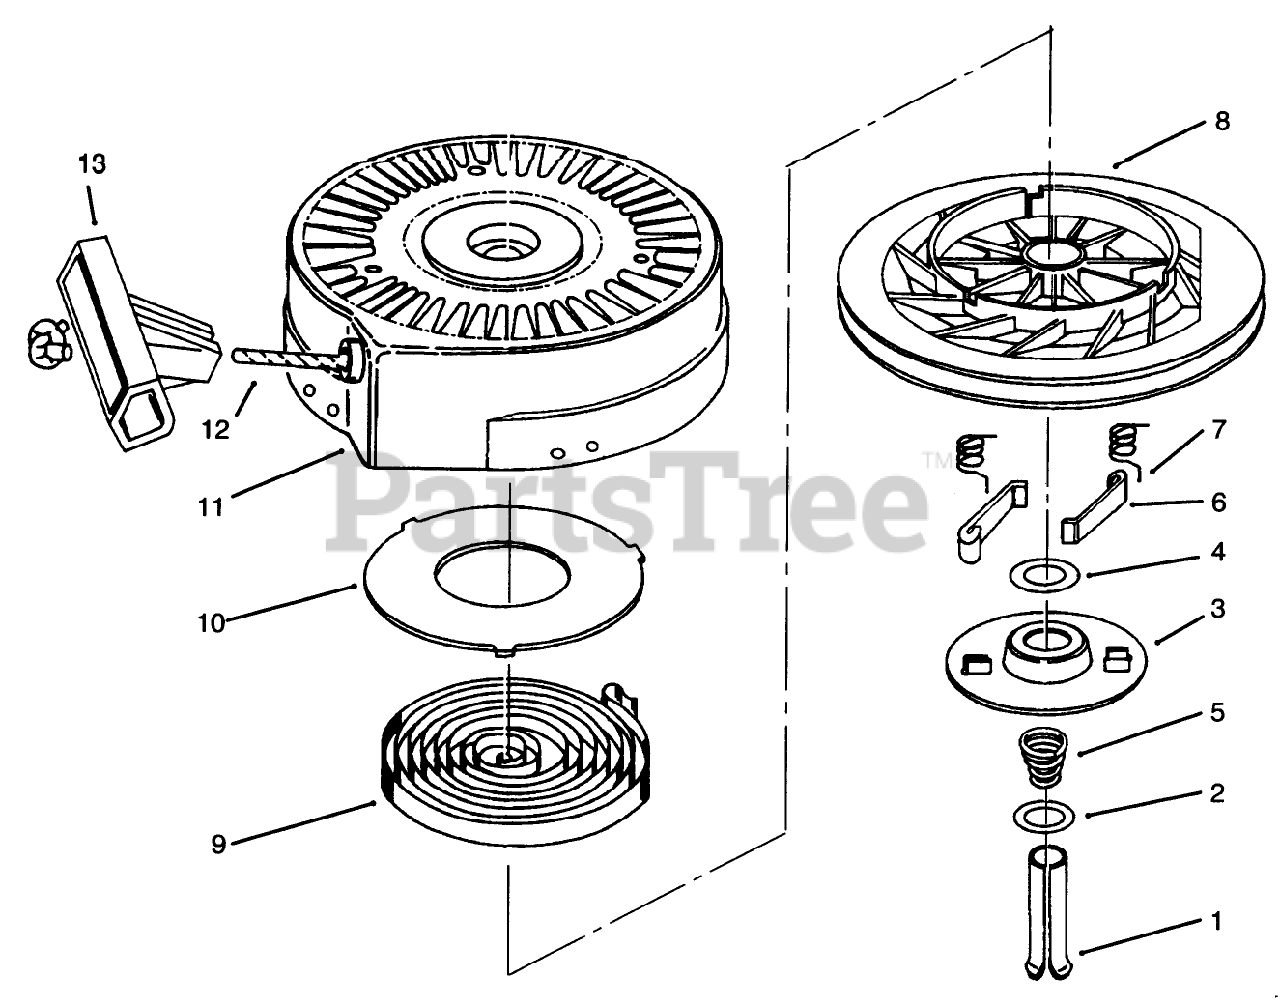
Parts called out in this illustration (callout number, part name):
1	Pin, Spring (Incl. Ref. #7)
2	Washer
3	Retainer
4	Washer
5	Brake Spring
6	Dog-Starter
7	Spring-Dog
8	Pulley and Rewind Spring ASM
9	Rewind Spring
10	Cover-Spring
11	Starter Housing ASM
12	Rope-Starter (98 cut to length)
13	Handle-Starter
